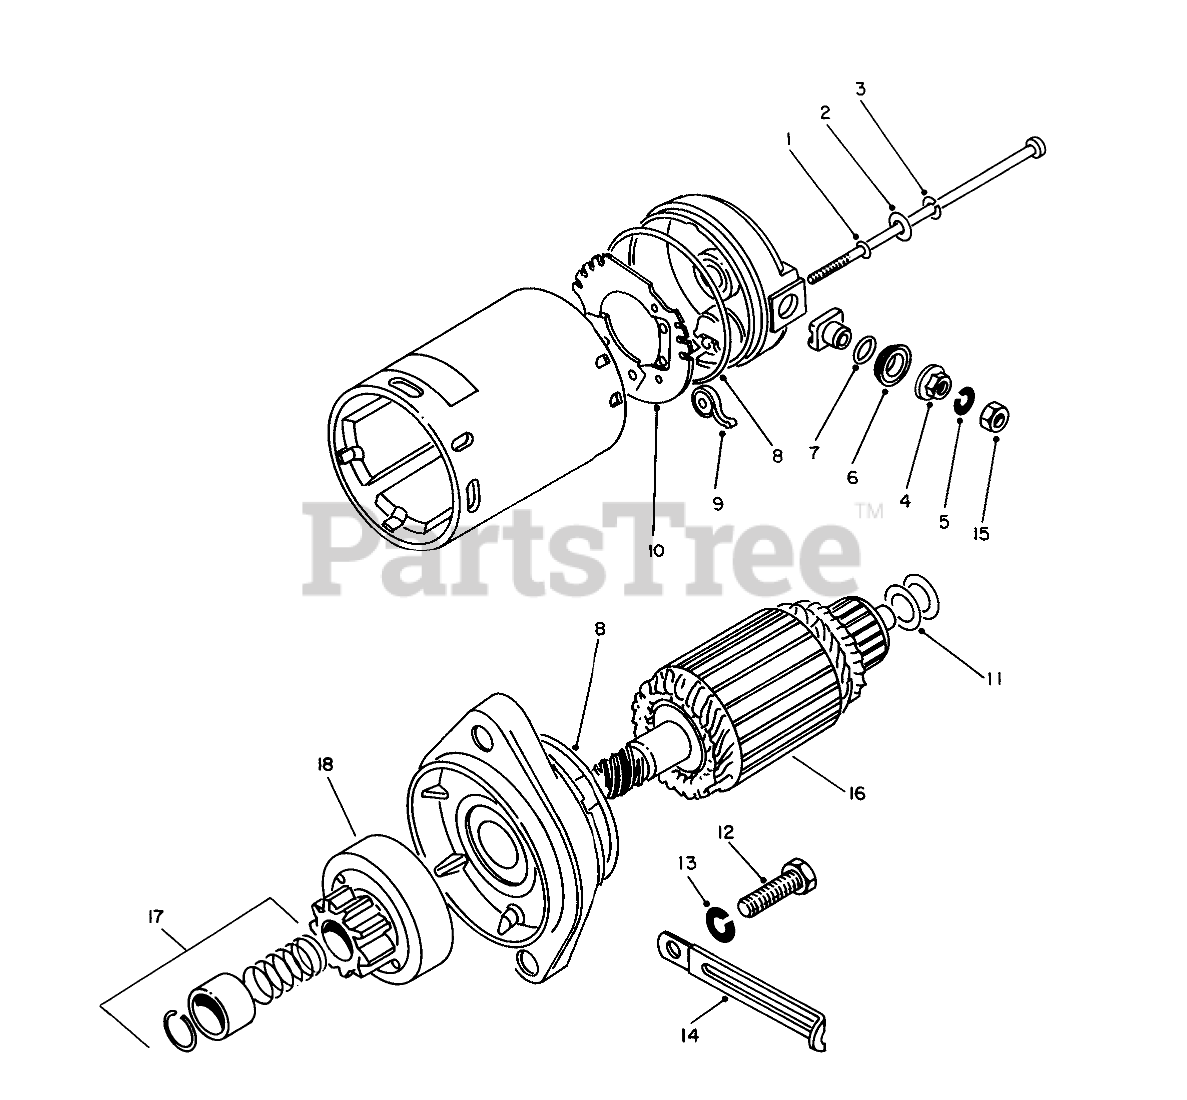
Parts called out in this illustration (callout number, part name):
1	0-Ring
2	Washer
3	Washer
5	LOCKWASHER
6	Bushing
7	0 Ring
8	0 Ring
9	Spring
10	Holder Assembly (Incl. Ref. #9)
13	Lockwasher
14	Clamp
16	Armature
17	Stopper Assembly
18	Pinion Assembly
